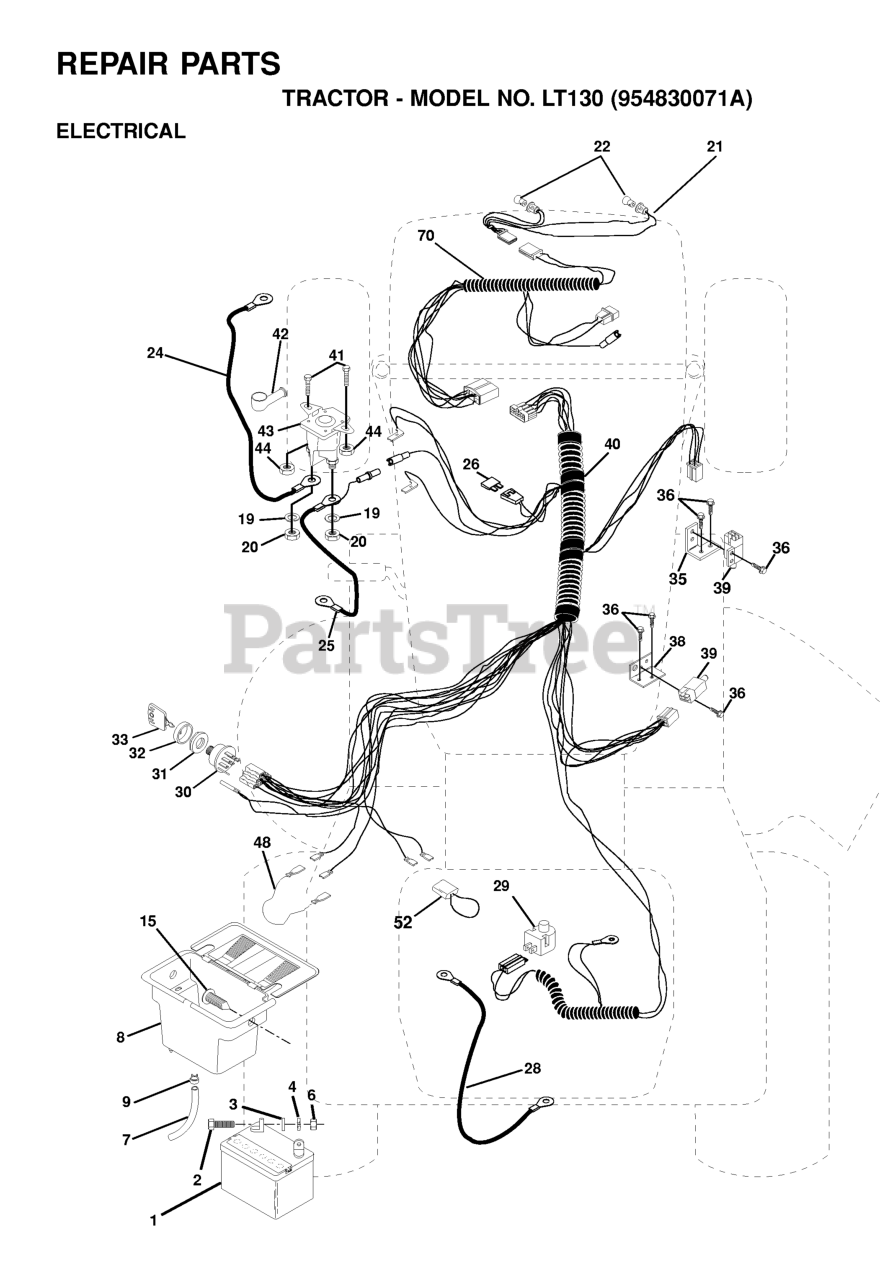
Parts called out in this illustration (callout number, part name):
1	BATTERY 12 VOLT 25 AMP
2	BOLT.HEX.1/4.X.3/4.DICHROMATE
4	LOCKWASHER
6	NUT
7	TUBE BATTERY DRAIN
8	BATTERY CASE
9	HOSE CLAMP T
15	FASTERER SNAP-IN
19	LOCKWASHER
20	NUT
21	HARNESS ASM HDLIG
24	BATTERY CABLE GT
25	CABLE BATTERY
28	CABLE T
29	RP.SWITCH.PLUNGER.NC.GRAY
30	SWITCH.IGNITION.4.POSITION
31	NUT IGNITION
32	COVER SWITCH KEY
33	KEY.MOLDED.GENERIC
35	BRACKET LT
38	SWITCH BRACKET
39	SWITCH INTERLOCKT
40	HARNESS IGNITION
41	BOLT
42	TERMINAL COVER
43	SOLINOID
44	Nut, Keps Blk Hex 1/4-20 UNC
48	ADAPTER.AMMETER
52	WIRE PROTECTION LOOP
70	ENGINE HARNESS
